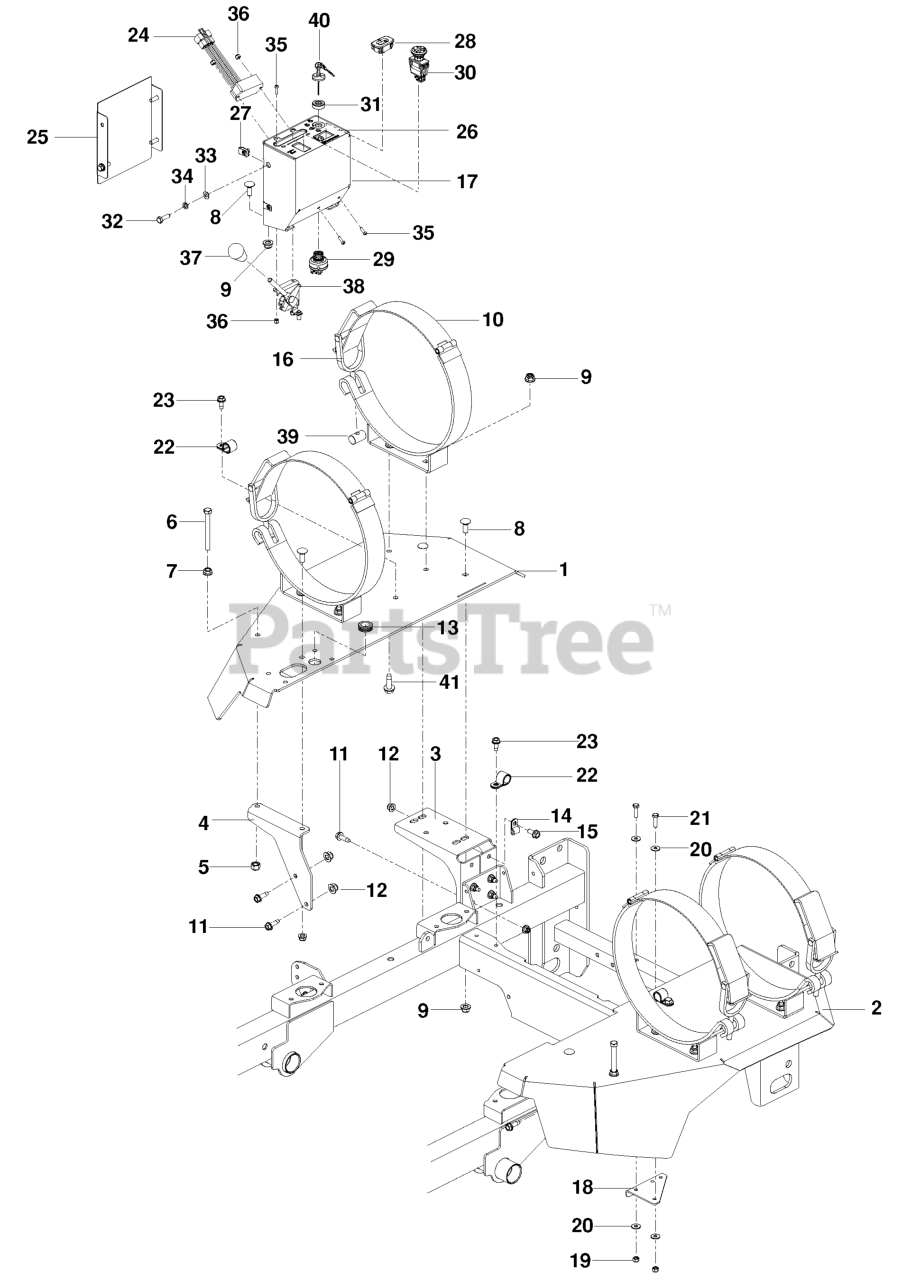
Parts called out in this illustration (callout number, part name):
1	FENDER, LP RH, ORG
2	FENDER, LP LT
3	MOUNT, TANK RR, BLK
4	SUPPORT.LP.FENDER.RH.BLACK
5	NUT 3/8C CENTERBLOCK
6	HCS 3/8-16 X 3-1/2 GR5 ZD
7	NUT 3/8C WHIZ
8	RHSNB 3/8C X 1
9	NUT 3/8-16 HEX FLG NYLOC ZD
10	LP TANK BRKT
11	RP BLT 5/16-18 X 1 THRD FORM D
12	5/16-18 NYLOC FLANGE NUT
13	GROMMET, FUEL LINE
14	DOUBLE TUBE CLAMP
15	HHFS 5/16-18 X 3/4
16	LP TOGGLE ASSY
17	DASH, LP, GRAY
18	BRACKET, REGULATOR, BLK
19	NUT.1/4-20.HEX.NYLOC.ZD
20	WASHER 1/4 FLAT
21	HCS 1/4 X 1
23	BOLT 5/16-18 X 3/4
24	TIMER, SEAT
25	COVER, LP DASH, GRAY
26	DECAL, LP CONTROL
27	U-CLIP 5/16-18 NUT RETAINER
28	HOUR METER
29	SWITCH, IGNITION, INDAK
30	SWITCH, PTO 10 AMP
31	CAP IGNITION NUT
32	HCS 5/16C X 1
33	FLAT WASHER 5/16 SAE
34	WASHER.LOCK.HVY.HLCL.SPR.5/16
35	SCR #10-24 X .75 SKT HD BLK
36	NUT 10-24 NYLOC
37	KNOB - SHIFT
38	CABLE, THROTTLE, 46"
39	NUT, TOGGLE, LP
40	KEY, IGNITION
41	HHFS 3/8-16 X 1 GRD 5 ZD
